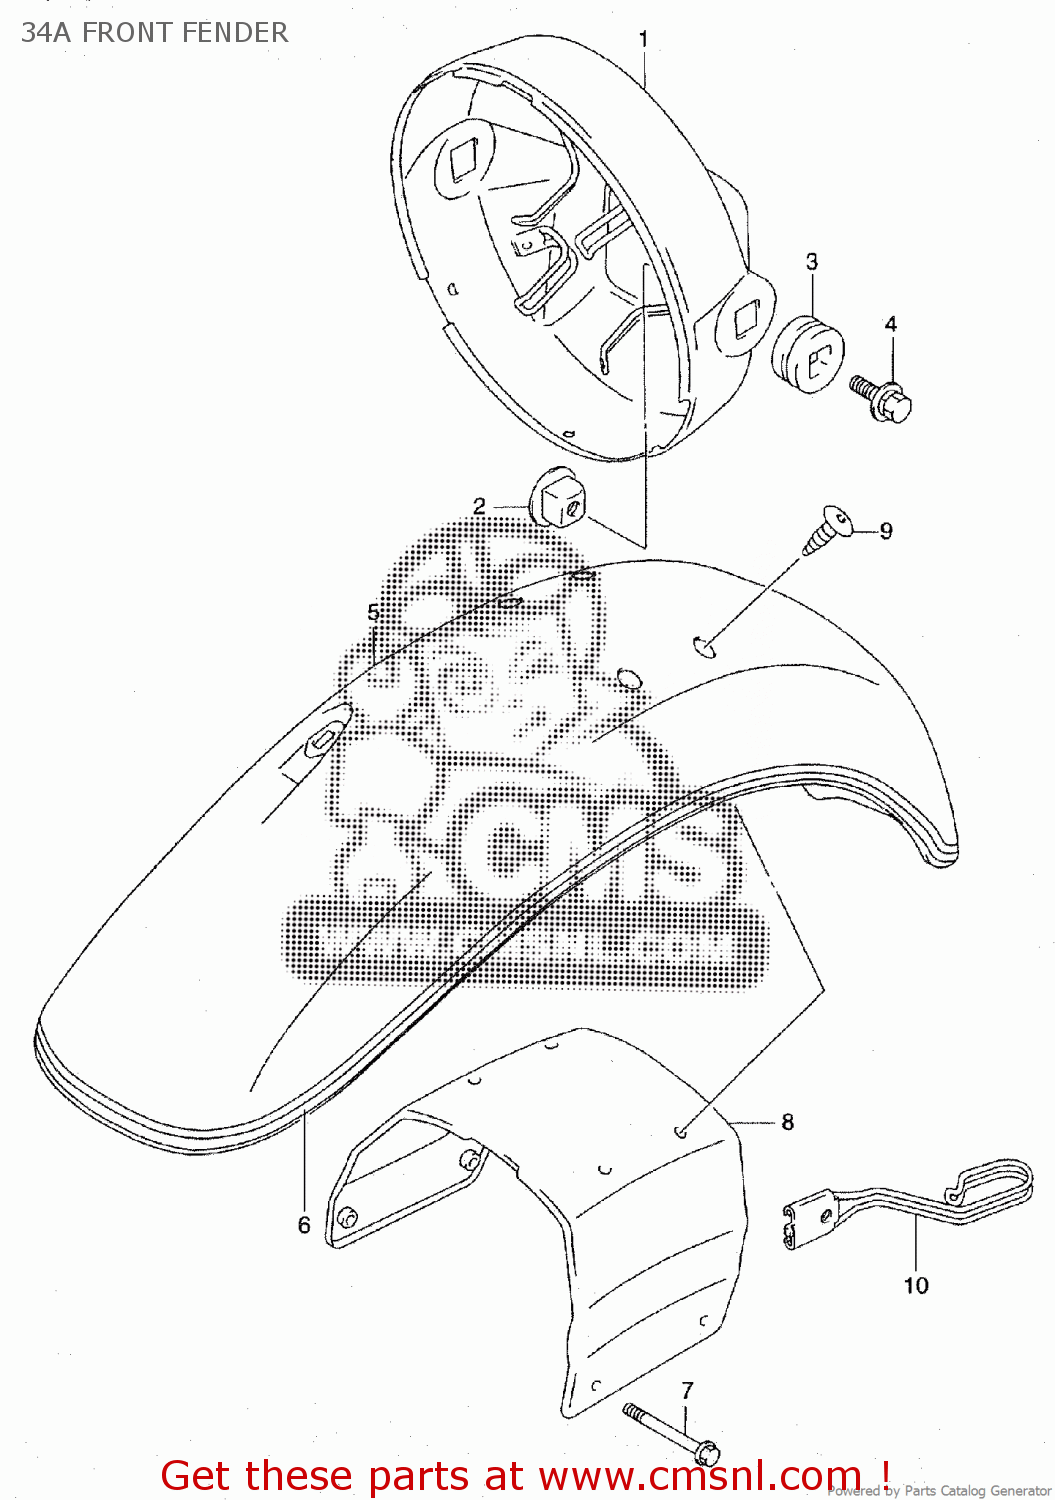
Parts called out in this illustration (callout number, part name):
1	HOUSING,HEADLAMP (COWLING)
2	SPACER,HEADLAMP HOUSING
3	CUSHION,HEADLAMP HOUSING
4	BOLT
7	BOLT
9	SCREW(5X16)
